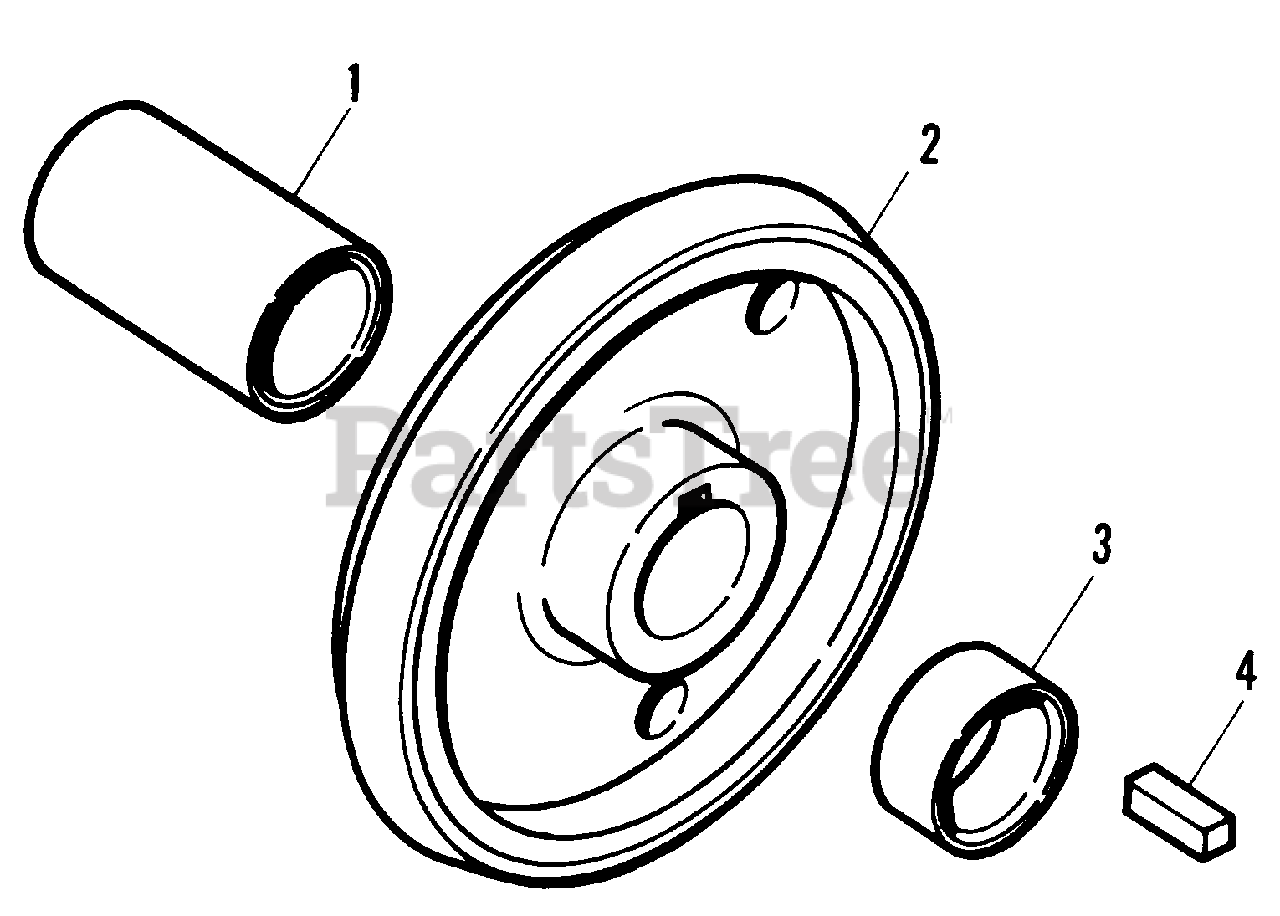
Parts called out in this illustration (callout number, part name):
1	SLEEVE, Pulley
2	PLATE ASSY., Clutch
4	KEY, Square
